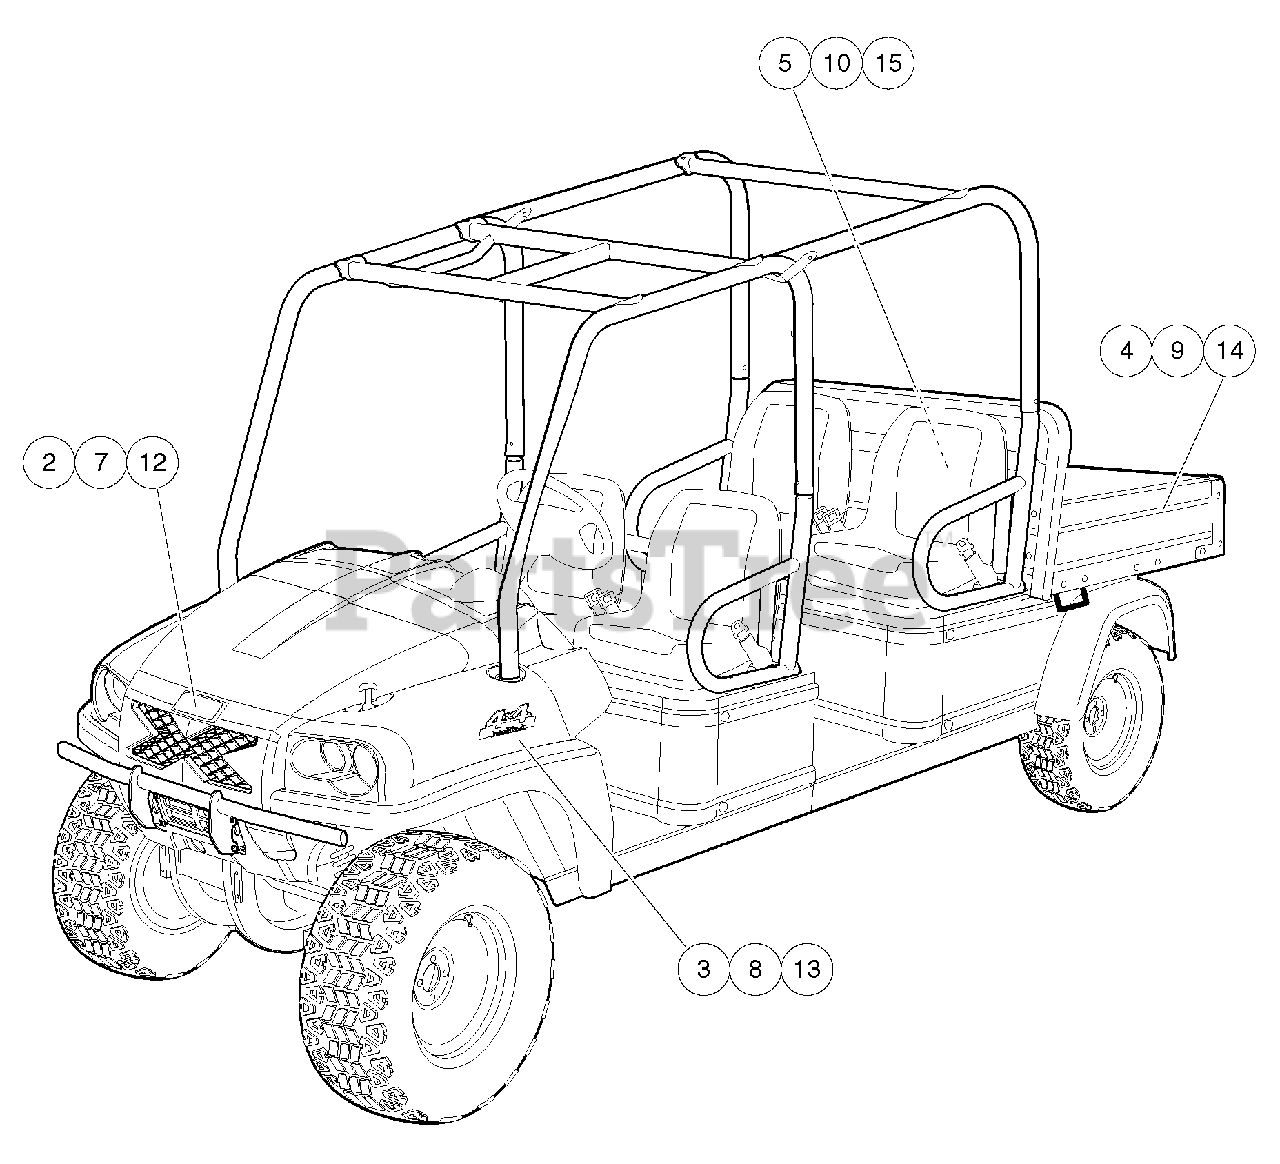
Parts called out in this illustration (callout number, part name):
1	Instl, Decal, Bed, XRT 1550 SE, Dk Green
2	Decal, Nameplate, CCI, Front
3	Decal, Badge, 4x4
4	Decal, Ds, XRT 1550 SE, Dk Green
5	Decal, PS, XRT 1550 SE, Dk Green
6	Instl, Decal, Bed, XRT 1550 SE, Red
7	Decal, Nameplate, CCI, Front
8	Decal, Badge, 4x4
9	Decal, Ds, XRT 1550 SE, Red
10	Decal, Ps, XRT 1550 SE, Red
11	Instl, Decal, Bed, XRT 1550 SE, Ntrl
12	Decal, Nameplate, CCI, Front
13	Decal, Badge, 4x4
14	Decal, Ds, XRT 1550 SE, Ntrl
15	Decal, Ps, XRT 1550 SE, Ntrl
